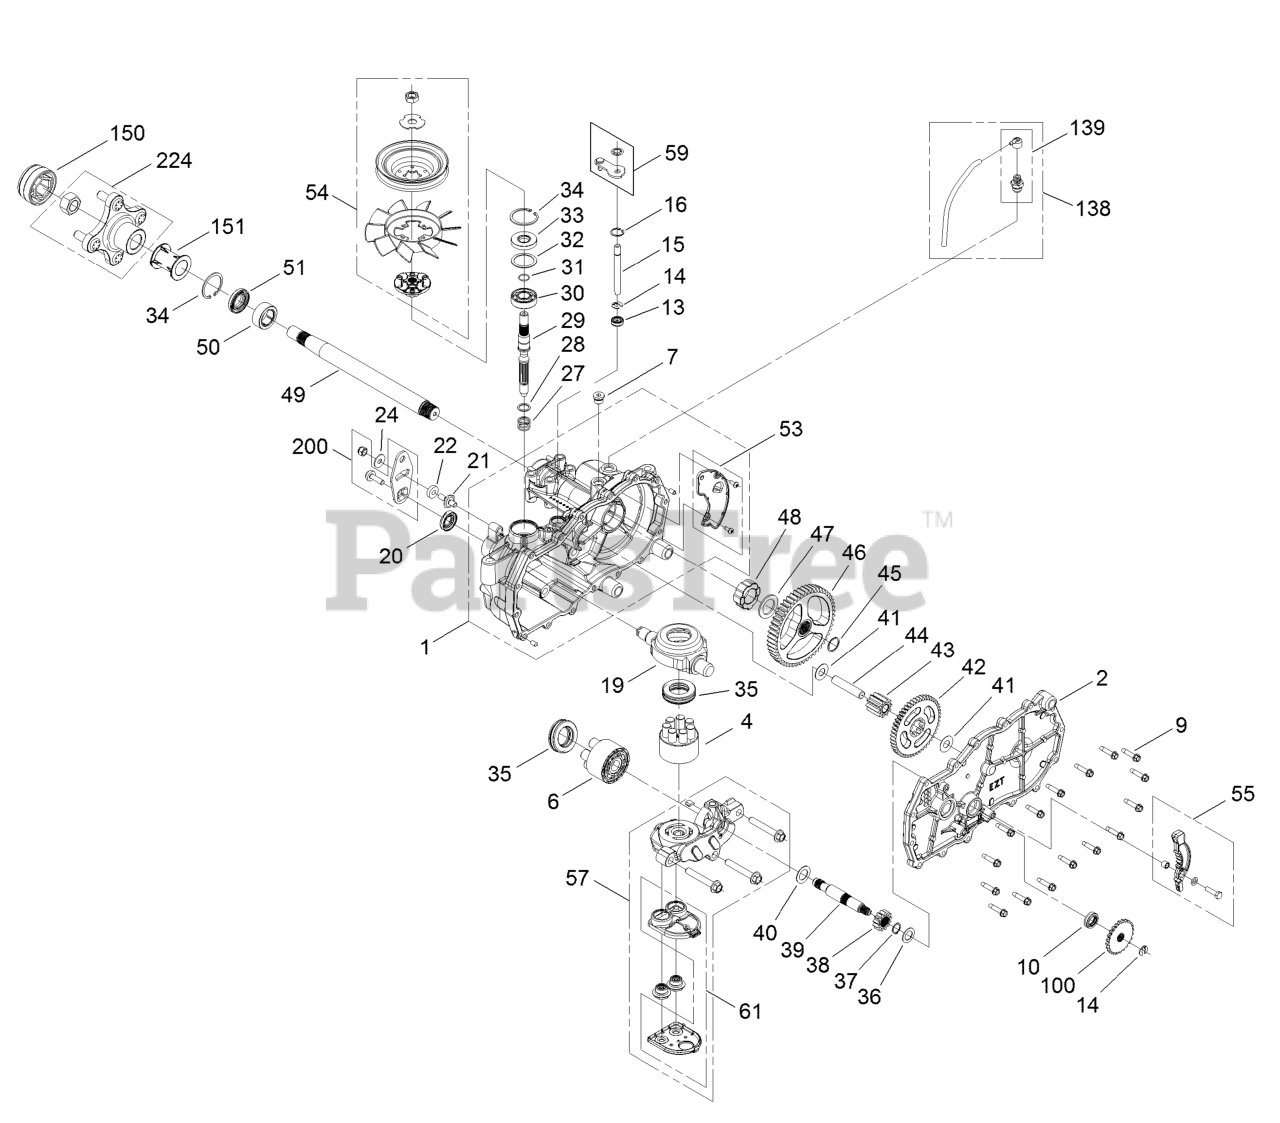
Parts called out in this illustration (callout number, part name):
1	MAIN HOUSING ASM
2	SIDE ASM
4	PUMP BLOCK ASM
6	CYLINDER BLOCK KIT
7	PLUG-THREAD, STRAIGHT
9	SCREW-HHF
10	SEAL-OIL
13	SEAL-LIP
14	RING-RETAINING, EXTERNAL
15	ROD-BYPASS
16	RING-RETAINING, INTERNAL
19	SWASHPLATE-TRUNNION
20	SEAL-LIP
22	PUCK-FRICTION
29	SHAFT-INPUT
30	BEARING-BALL
31	RING-RETAINING
33	SEAL-LIP
34	RING-RETAINING
35	BEARING-THRUST
36	WASHER-FLAT
37	RING-RETAINING
38	GEAR-PINNION, 13T
39	SHAFT-MOTOR
41	Washer
42	GEAR-10T/48T
43	GEAR-JACKSHAFT, 10T
44	PIN-JACKSHAFT
45	RING-SPIRAL, RETAINING
46	GEAR-52T, BULL
48	BEARING-SLEEVE
49	SHAFT-AXLE
50	BUSHING-AXLE
51	SEAL-LIP
53	EXPANSION PLATE KIT
55	BRAKE ARM KIT
57	CENTER SECTION FILTER KIT
59	BYPASS KIT
61	FILTER KIT
100	DISC-BRAKE, COG
138	BREATHER KIT
139	BREATHER ASM
150	COVER-NUT, AXLE
151	TUBE-AXLE
200	CONTROL ARM KIT
